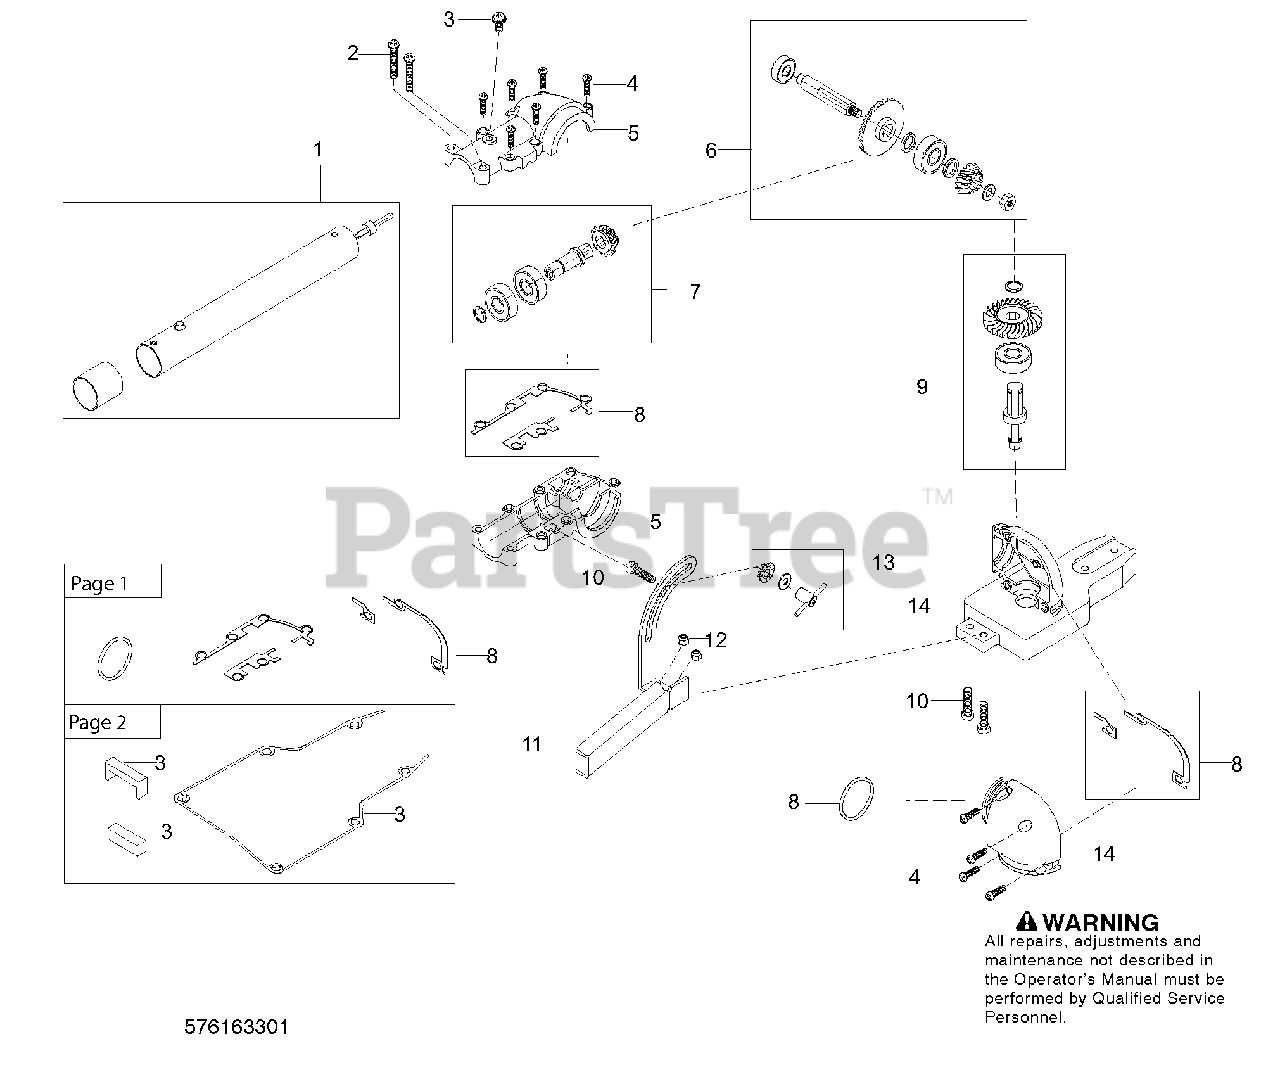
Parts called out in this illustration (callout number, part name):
1	KIT - CONNECTION STICK
2	SCREW 2 PACK 9SXAZM05-30
3	SCREW 1 PACK 9SDAZM05-10
4	SCREW 16 PACK 6SQAZ-04-14
5	KIT - STICK HOUSING
6	KIT - GEAR
7	KIT - INPUT SHAFT / GEAR
8	KIT - GASKET
9	KIT - OUTPUT SHAFT / GEAR
10	SCREW 3 PACK 9SXAZ-05-20
11	HANDLE 9068-A10601
12	NUT 6NGZ-05
13	KIT - LOCKING HANDLE
14	KIT - BLADE HOUSING
